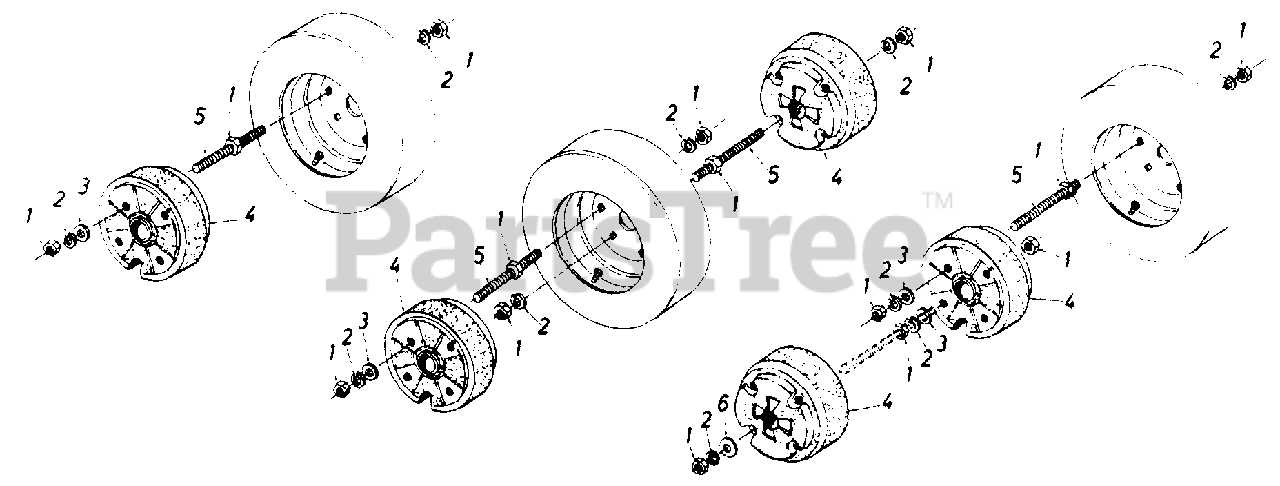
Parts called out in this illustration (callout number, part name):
1	Hex Nut 1/2-13 Thd.
2	Lock Washer 1/2 I.D.
3	Flat Washer .53 I.D. x .93" O.D.
4	Wheel Weight
5	Rod Threaded 1/2-13 x 9.50 Lg.
6	Fl -Washer .50 I.D. x 2.00 O.D.
